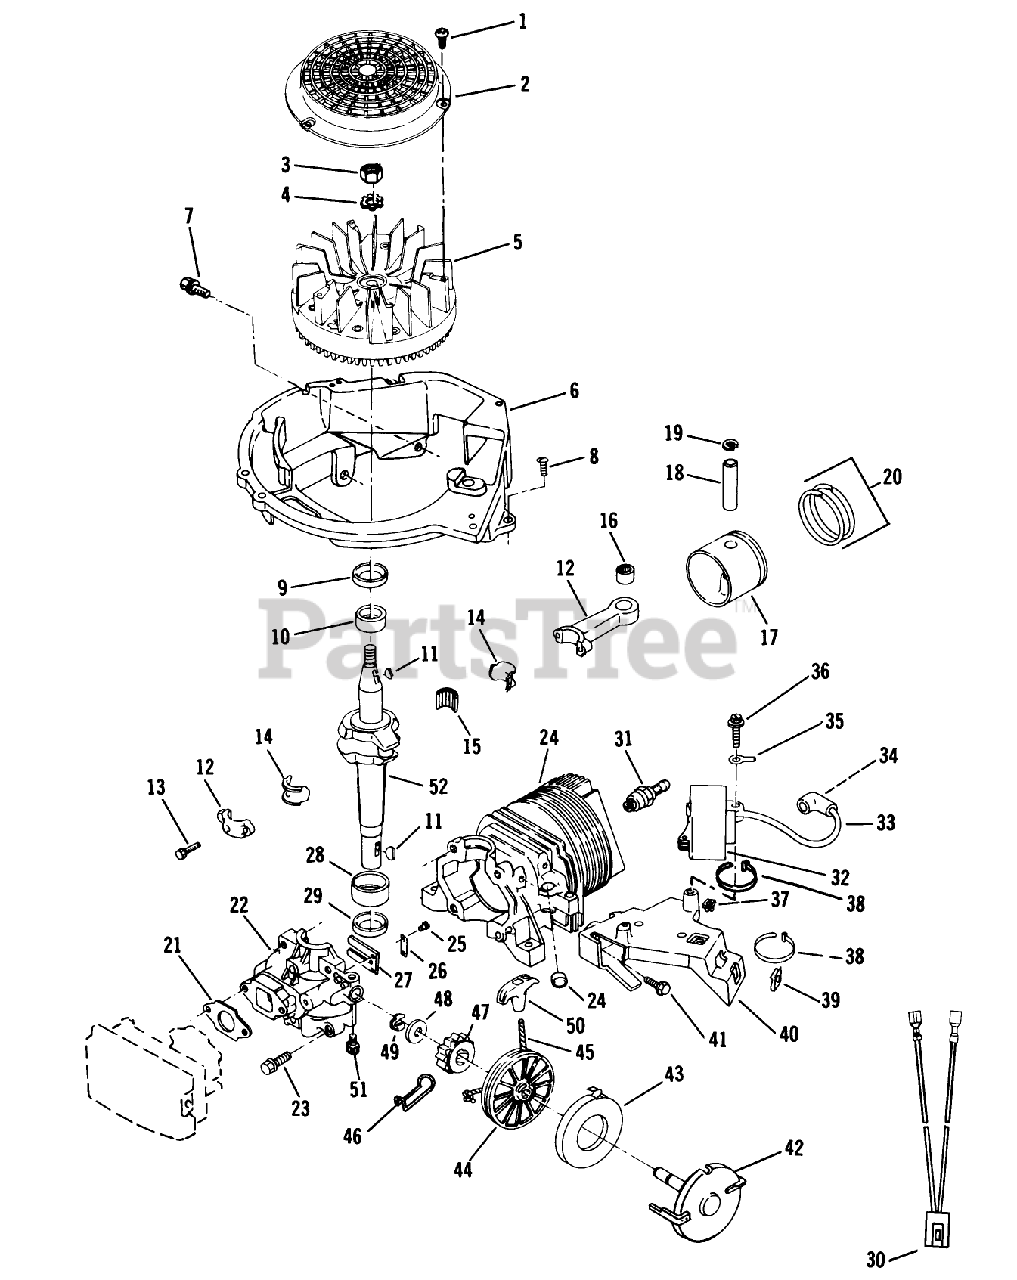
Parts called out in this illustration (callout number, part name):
1	SCREW F
2	SCREEN F'WHEEL S
7	SCREW-SEMS
8	SCREW F
10	BEARING V
13	SCREW-HSH
14	LINER ASM
16	BEARING AY F
19	RING-RETAINING
21	GASKET CARB S
23	SCREW S
24	PLUG-CORE VF
26	PLATE-BACKUP, REED
28	BEARING V
29	SEAL-OIL
33	HT LEAD&COVER XEV
35	TERMINAL S
37	NUT-CLIP
39	NUT - SPEED S
42	SPRING CUP&PIN S
43	SPRING&RET.AY S
44	PULLEY STARTER S
48	WASHER S
50	HANDLE STARTER S
